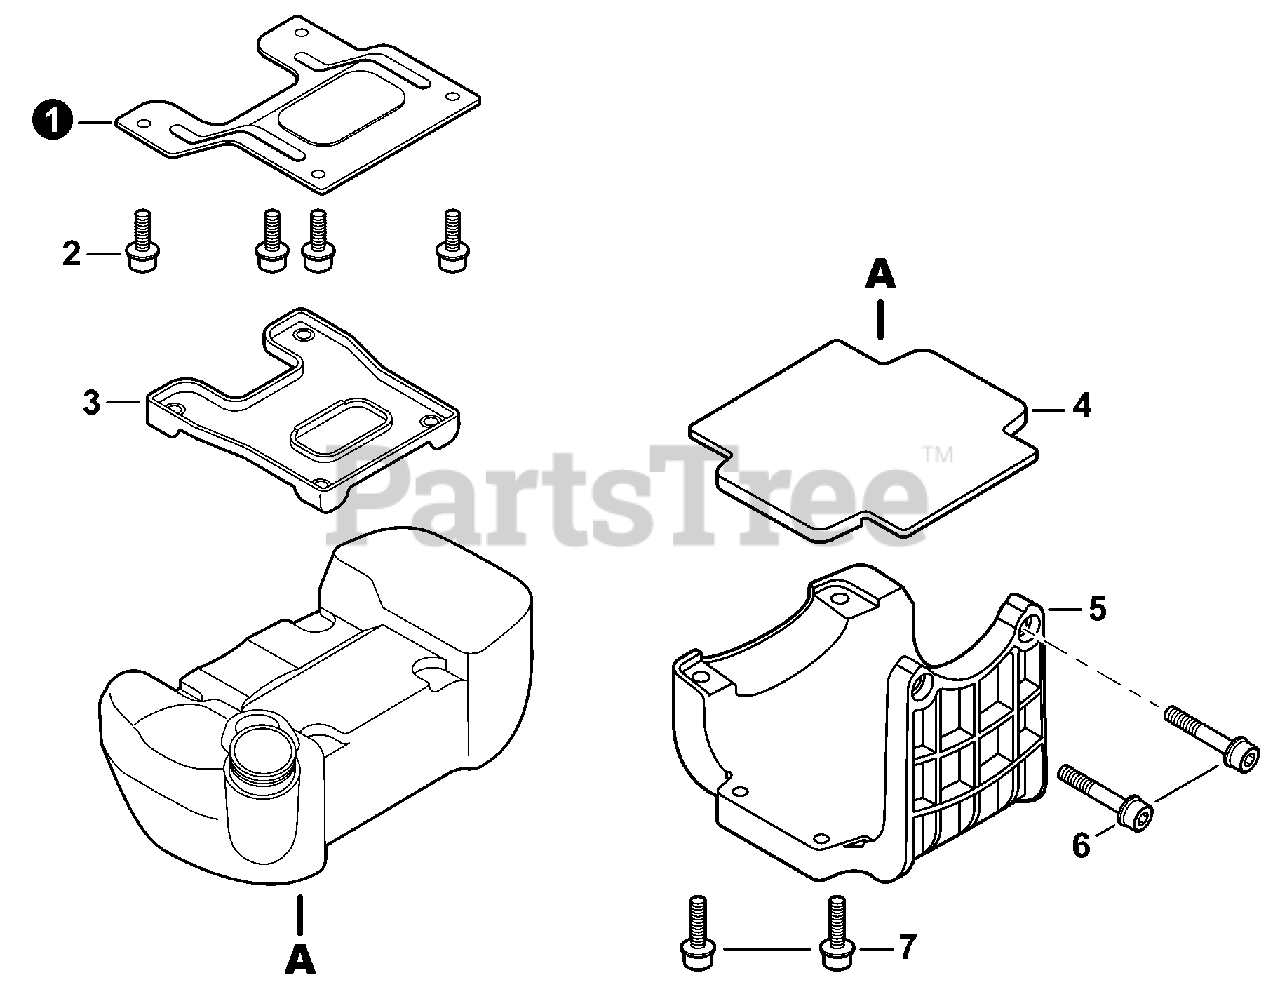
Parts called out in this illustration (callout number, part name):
1	BRACKET, FUEL TANK
2	BOLT 5×12
3	CUSHION, UPPER
4	CUSHION, FUEL TANK
5	GUARD, FUEL TANK
6	BOLT 5×25
7	BOLT 5×20
